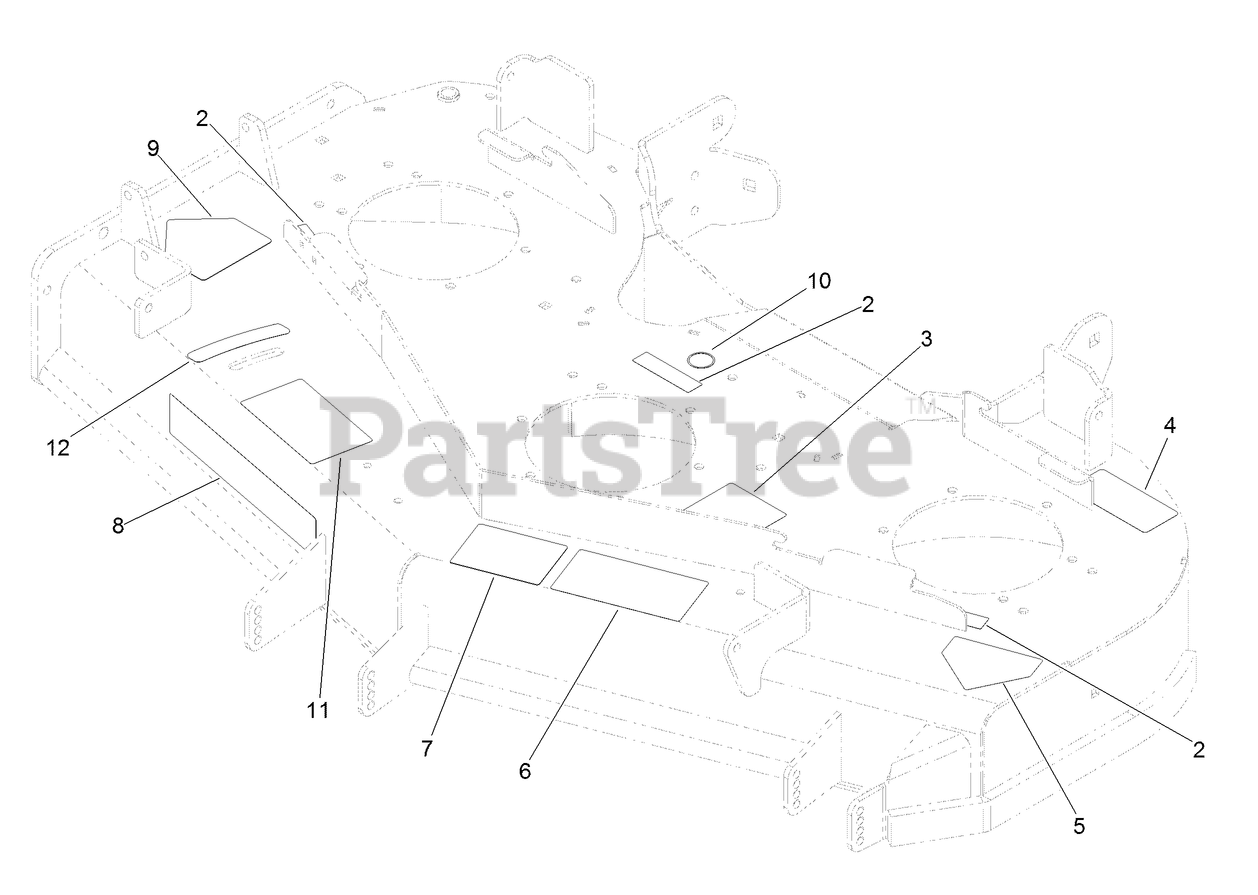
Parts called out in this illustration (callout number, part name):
2	DECAL-COVER, MISSING
3	DECAL-ROUTING, DECK BELT
4	DECAL-TORQUE
5	DECAL-DANGER
6	DECAL-DANGER, THROWN OBJECT
7	DECAL-SCALP, ANTI
9	DECAL-DANGER
10	DECAL-GREASE
11	DECAL-ADJUSTMENT, BAFFLE
12	DECAL-SETTING, BAFFLE
